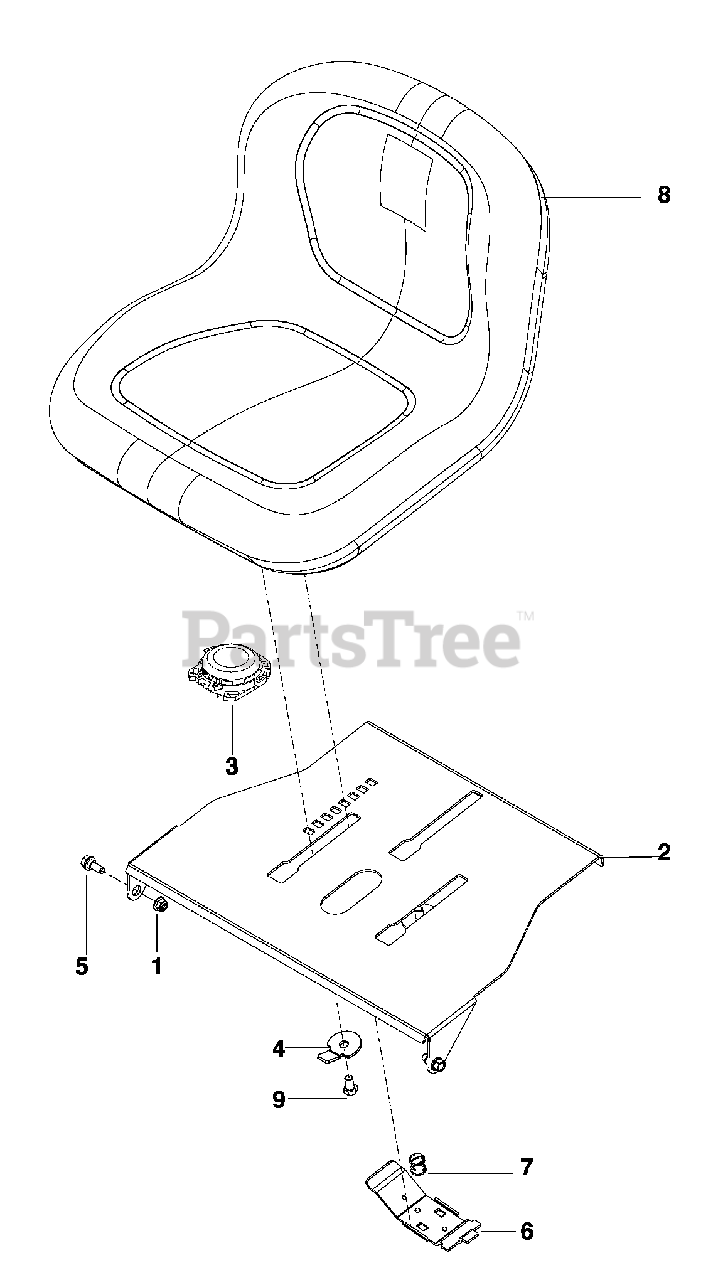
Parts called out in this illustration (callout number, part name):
1	NUT 5/16-18 FLANGE NYLOC
2	PLATE, SEAT
3	SWITCH, SEAT N/C
4	STOP, SEAT
5	BOLT 5/16-SHOULDER
6	HANDLE, SEAT SLIDE
7	SPRING, SEAT SLIDE
8	SEAT
9	BOLT, HEX HD 3/8-16 x 5/8
